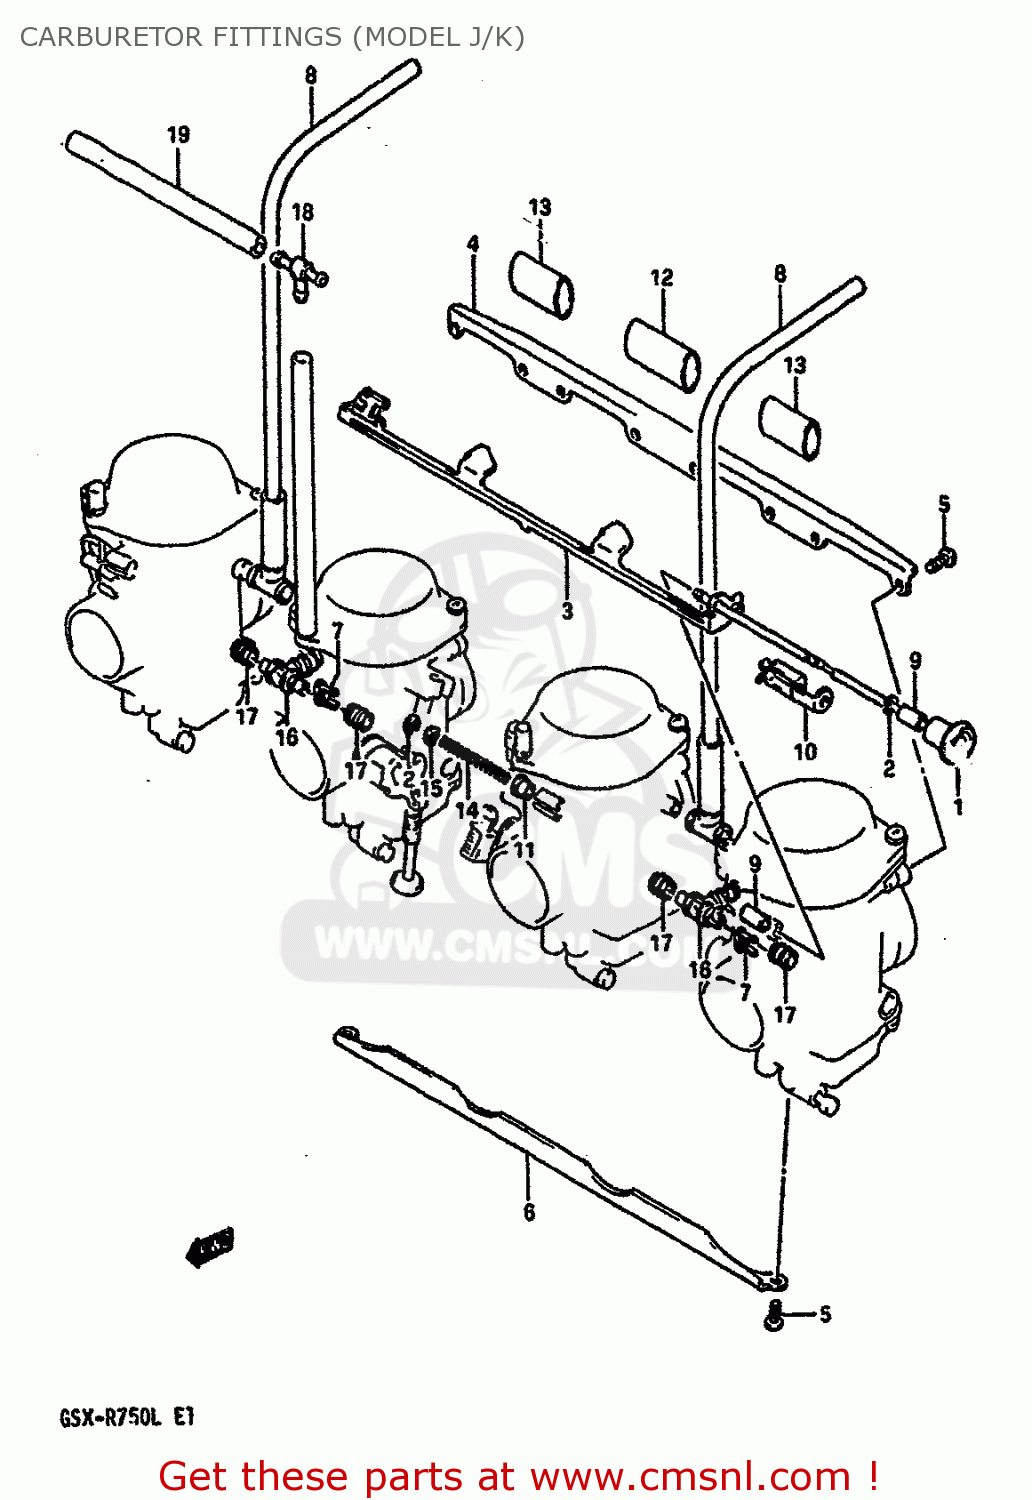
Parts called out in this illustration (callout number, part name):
1	SHAFT ASSY,STARTER
2	E RING
3	LEVER
4	PLATE
5	SCREW
6	PLATE
7	HOLDER
8	HOSE
9	RING
10	PLATE
11	RING
12	NUT
13	HOSE
14	SPRING
15	WASHER
16	NIPPLE
17	HOSE
18	LEVER
19	HOSE
20	SHAFT ASSEMBLY
21	SEAL
22	GASKET,THROTTLE SHAFT (NAS)
23	ADJUSTER
24	SCREW
25	VALVE,THROTTLE(125)
26	GASKET,FLOAT CHAMBER (MCA)
27	JET,PILOT(37.5)
28	JET,NEEDLE(Y-5)
29	O RING
30	JET,MAIN(112.5)
31	PLUG,DRAIN
32	FLOAT/NEEDLE VALVE ASSY
33	O RING
34	O-RING,NEEDLE VALVE
35	SCREW
36	SCREW
37	SPRING
38	SPRING
39	CAP
40	CLIP
41	SHAFT ASSEMBLY
42	RING
43	COVER,DIAPHRAGM
44	CAP,STARTER
45	HOSE
46	SCREW
47	SPRING
48	WASHER
49	HOLDER,GUIDE
50	SPRING
51	PLUNGER ASSY
52	JET,AIR
53	SCREW,PILOT
54	SPRING
55	WASHER
56	O RING,PILOT AIR SCREW
